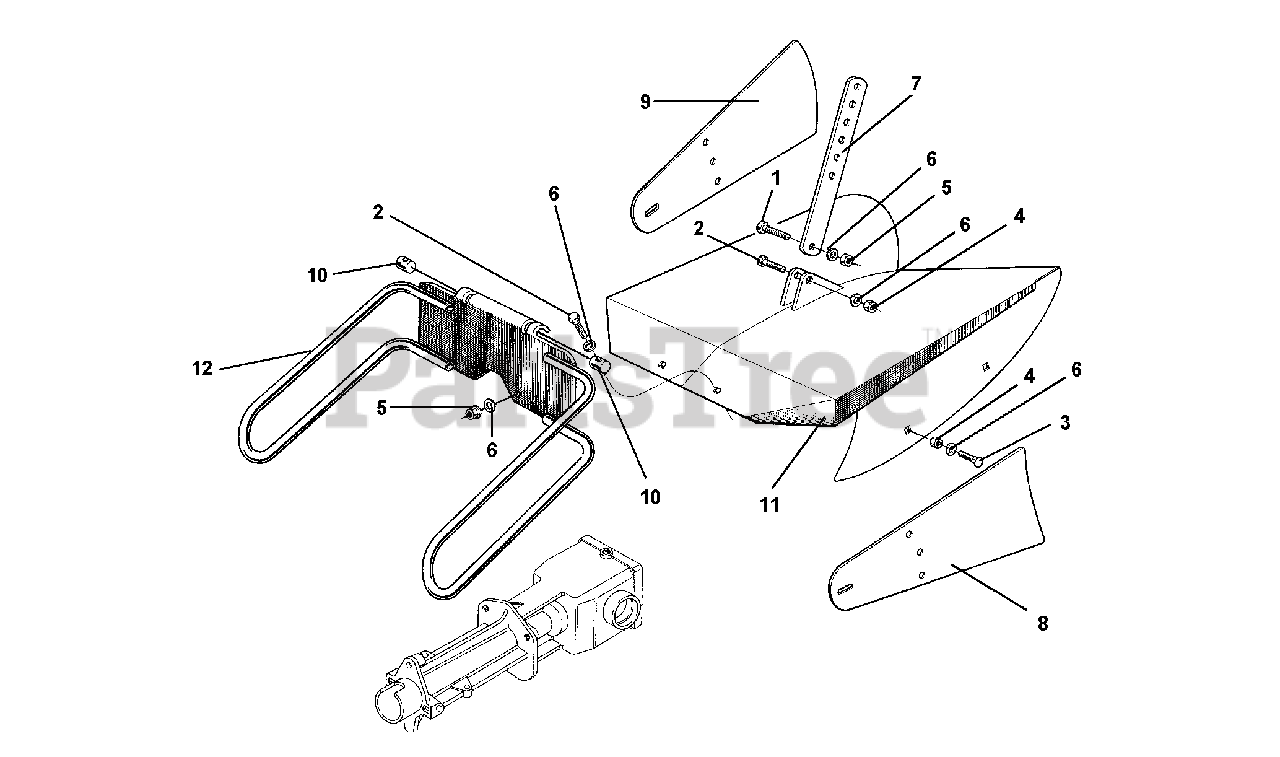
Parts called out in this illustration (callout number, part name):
1	SCREW M8 X 25
2	SCREW TE M8 X 30
3	SCREW TTQ M8 X 20 UNI 5731
5	NUT, SELF LOCKING M8
6	WASHER, LOCK 8.4
7	ROD SUPPORT
8	L.H. REAR FLAP
9	R.H. REAR FLAP
11	CASING CENTRAL
12	RIDGER COUPLING
